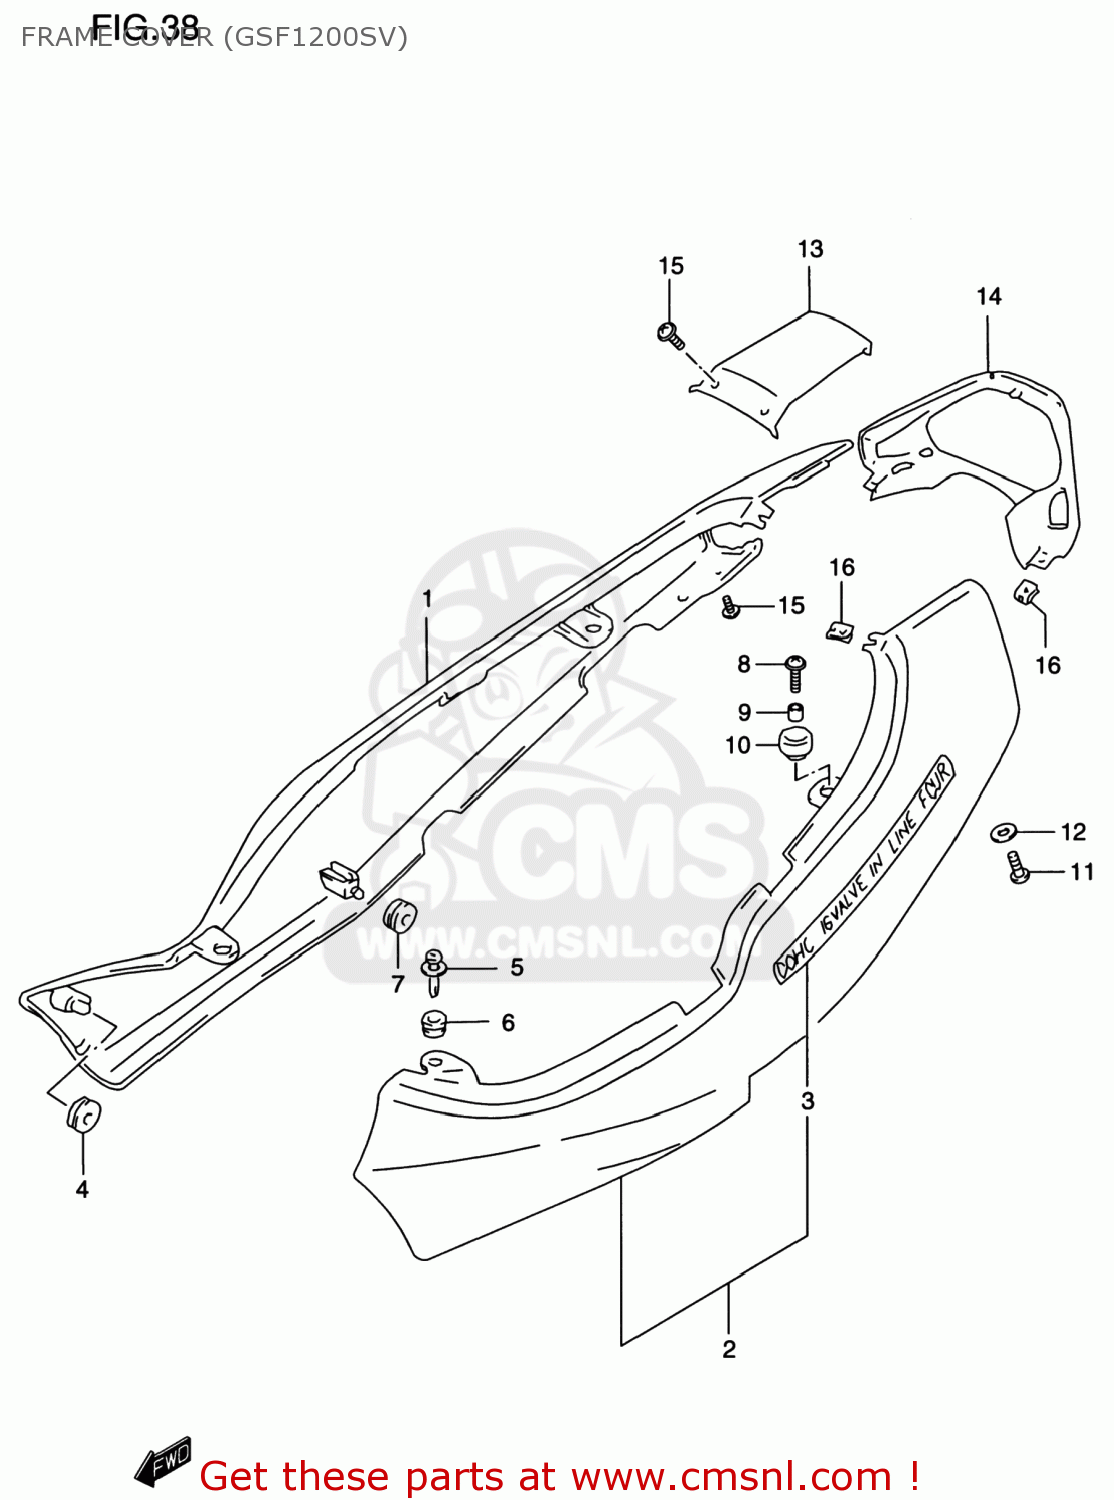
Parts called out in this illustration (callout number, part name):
1	COVER,FRAME,R(BLUE)
2	COVER,FRAME,L(BLUE)
3	EMBLEM,FRAME COVER
4	CUSHION,FRAME COVER FR
5	CLIP
6	CUSHION
7	CUSHION
8	SCREW(6X20)
9	SPACER(6.5X10X9.4)
10	CUSHION
11	SCREW
12	WASHER(6.3X16X1.5)
13	COVER,FRAME CTR
14	COVER,FRAME RR
15	SCREW
16	NUT
